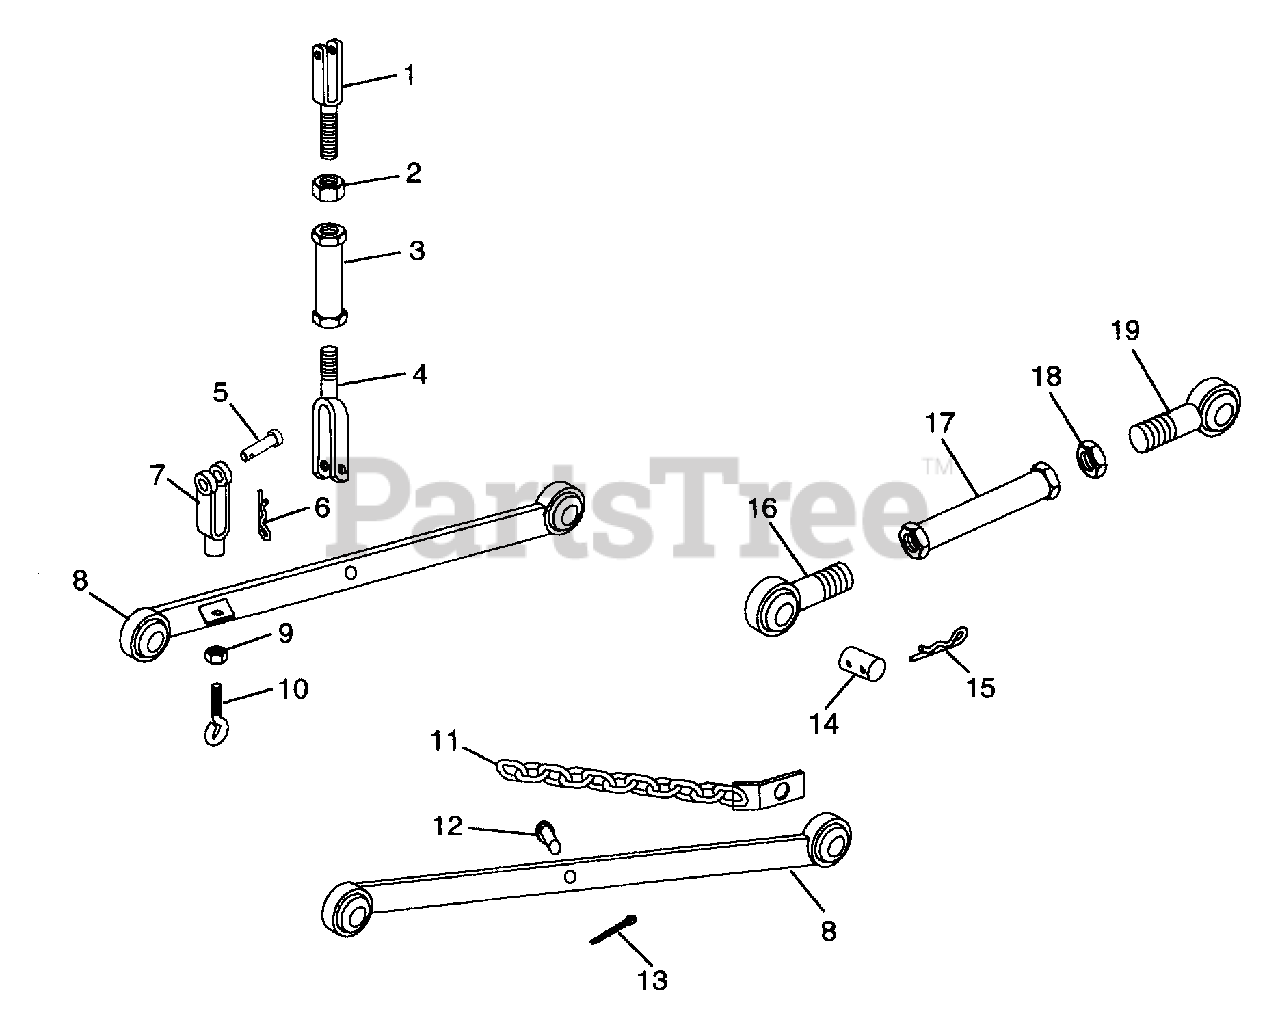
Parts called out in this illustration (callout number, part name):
1	CLEVIS R.H.
2	NUT-JAM .625-11
3	TURNBUCKLE
4	CLEVIS L.H.
5	CLEVIS PIN
6	PIN-HAIR INT .09X.188 PL
7	YOKE, .312-24 X 2.25 ZN PL
8	LOWER ARM
9	NUT-HEX .312-24 PL
10	EYE-BOLT
11	SWAY CHAIN
12	PIN-CLEV .50X1.25 RH ST PL
13	PIN-COTR .12 X 1.25 PL
15	PIN-HAIR INT .14X.4X2.75
16	BALL JOINT L.H.
17	TURNBUCKLE
18	NUT-JAM .75-10 PL
19	BALL JOINT R.H.
